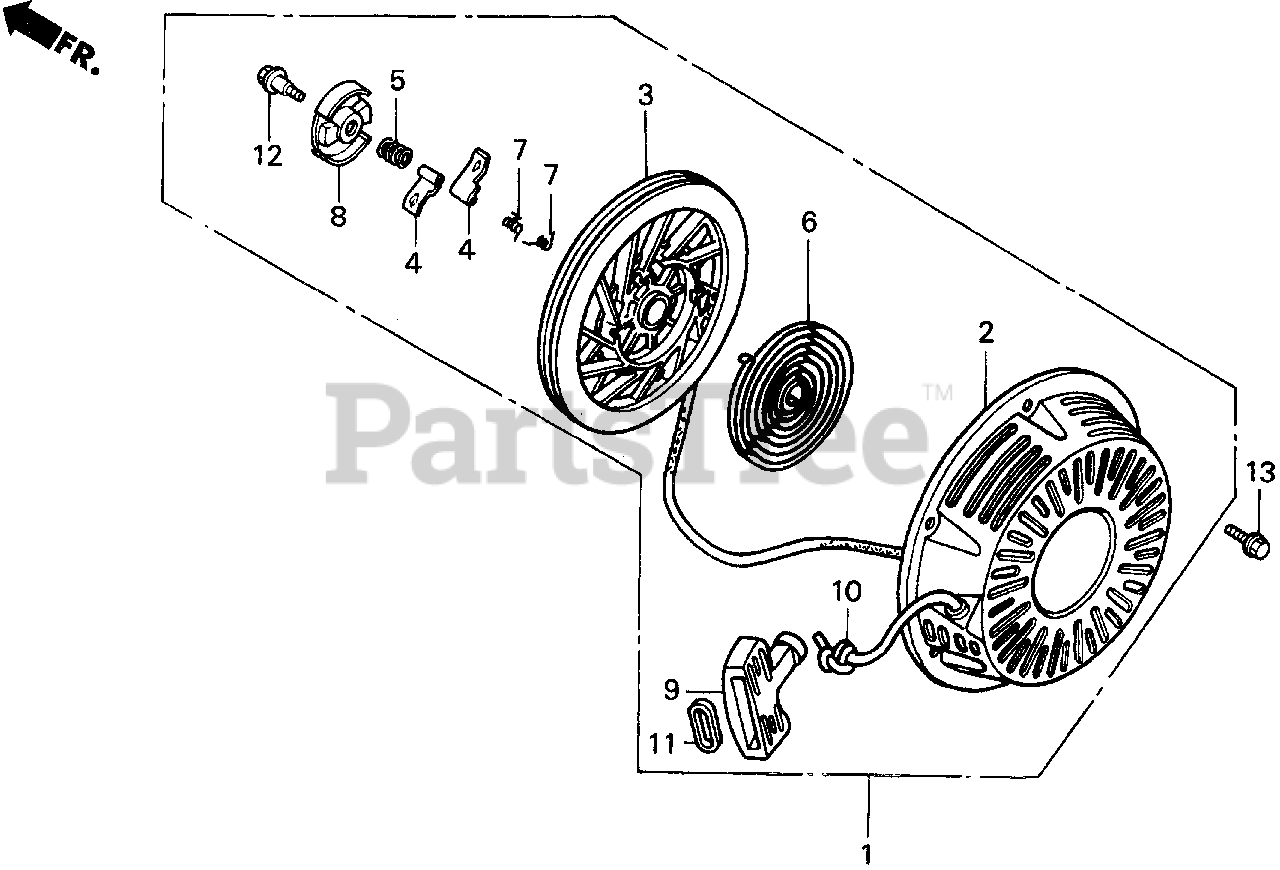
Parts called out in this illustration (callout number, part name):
1	STARTER ASSY., RECOIL *NH1* (BLACK)
2	CASE, RECOIL STARTER *NH1* (BLACK)
3	PULLEY, RECOIL STARTER
4	RATCHET, STARTER
5	SPRING, FRICTION
6	SPRING, STARTER RETURN
7	SPRING, RATCHET
8	RETAINER, SPRING
9	GRIP, STARTER
10	ROPE, RECOIL STARTER (#5X55") (NA USE ALT:08550-ZG921-11)
10	ROPE, RECOIL STARTER (#5X55")
11	GRIP, REINFORCEMENT
12	SCREW, CENTER
13	BOLT, FLANGE (6X10)
